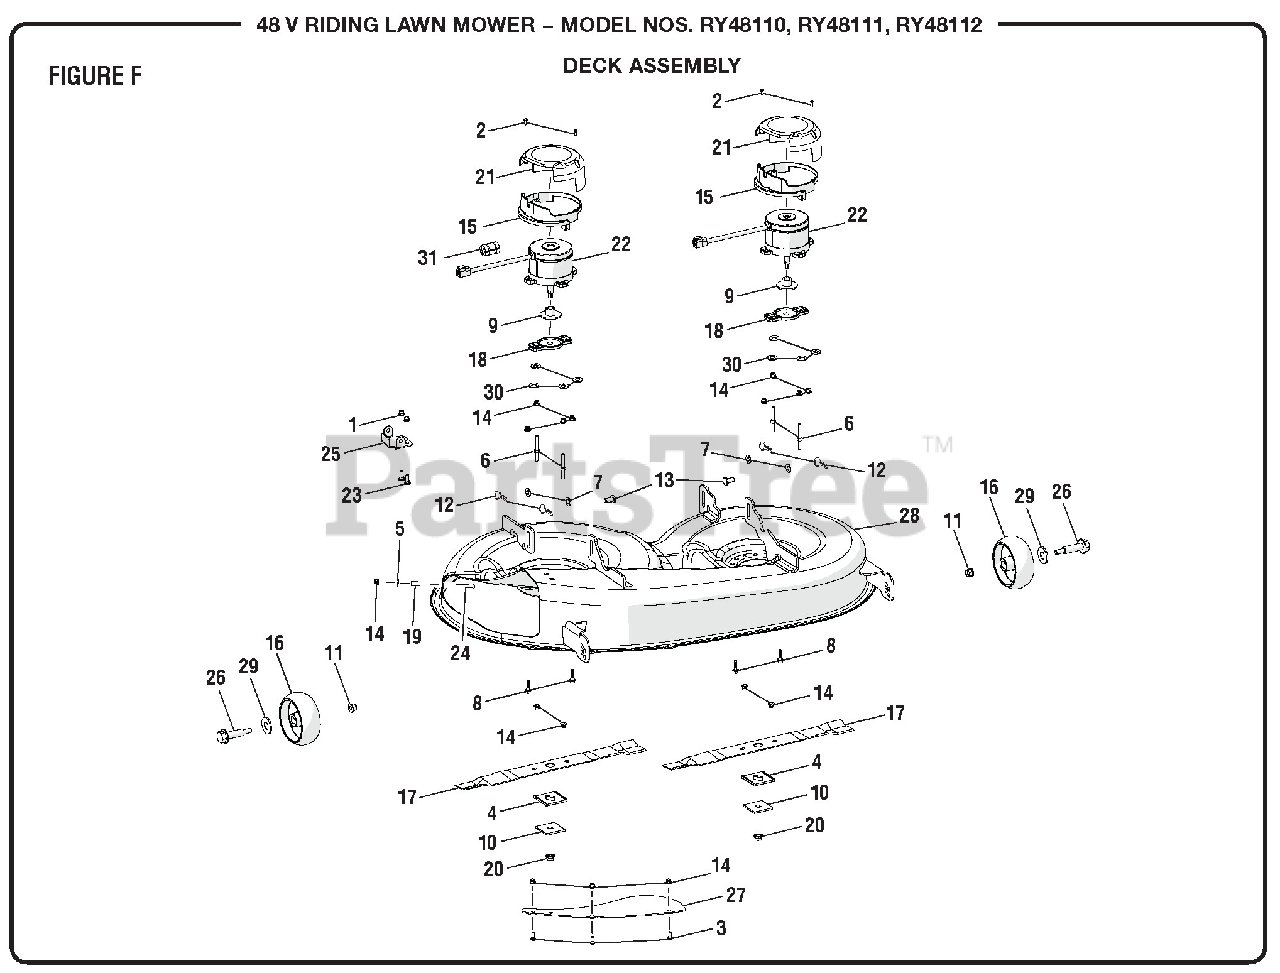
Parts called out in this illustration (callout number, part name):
1	Flange Nut (M8 x 1.25)
2	Screw (M4.2 x 13 mm)
3	Carriage Bolt (M6 x 16 mm)
4	Blade Spacer
5	Washer (OD18 x ID6.4 x 1.6t)
6	Threaded Stud (M6 x 35 mm)
7	Washer (OD20 x ID10.5 x 2t)
8	Flange Bolt (M6 x 25 mm, Hex Hd.)
9	Motor Axle Bushing
10	Metal Blade Retainer
11	Lock Nut (M10 x 1.5 mm)
12	Cotter Pin (10 mm)
13	Lifting Plate Pin
14	Flange Lock Nut (M6 x 1.00)
15	Motor Cover
16	Front Deck Roller Wheel (124.5 Dia.)
17	Mulching Blade
18	Blade Holder
19	Deck Bagger Chute Mounting Shaft
20	Flange Lock Nut (M10 x 1.25)
21	Motor Cover Cap
22	Deck Motor
23	Carriage Bolt (M8 x 20 mm)
24	Screw (M6 x 40, Soc Hd.)
25	Mounting Mulch Door Bracket
26	Shoulder Bolt (M10 x 70 mm)
27	Butterfly Bracket
28	Mower Deck w/Brackets
29	Spring Washer (OD20.5 x ID17 x 0.3t)
30	Washer (OD18 x ID6.4 x 3t)
31	Magnetism Ring
